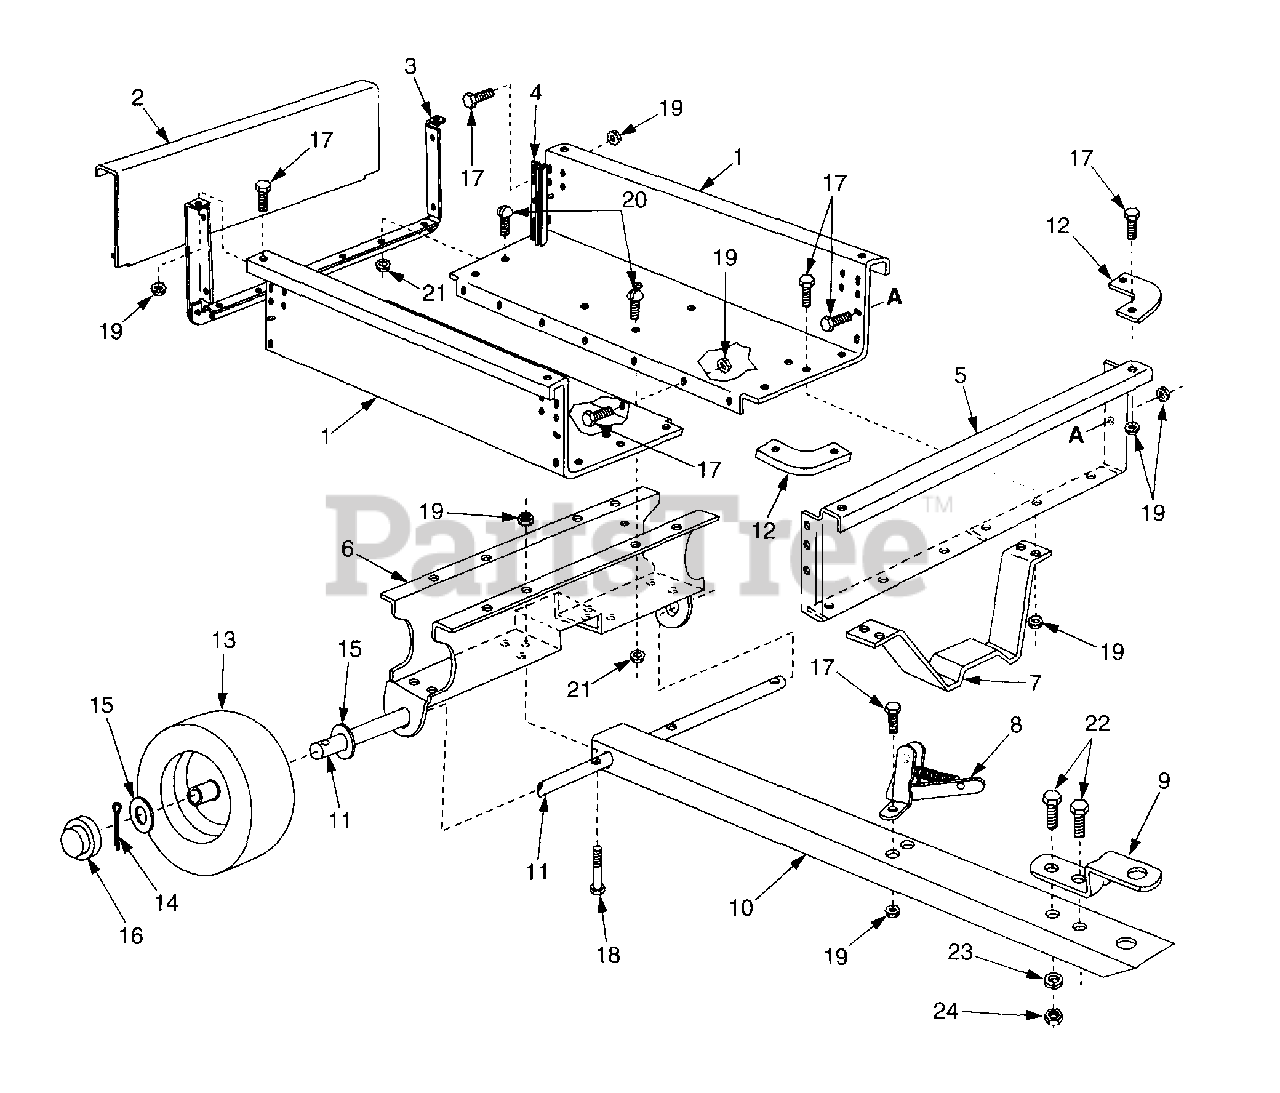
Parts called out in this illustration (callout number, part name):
15	Washer, Flat 3/4"
16	Hub Cap
17	Hex Bolt, 1/4-20 x 1/2"
18	Hex Bolt, 1/4-20 x 1-1/2"
19	Hex Nut, 1/4-20 Thread (Sems)
20	Slt. Truss Hd. Bolt 5/16-18 x 3/4" Lg.
21	Hex Nut, 5/16-18 Thread (Sems)
22	Hex Bolt, 3/8-16 x 1" Lg.
23	Lock Washer, 3/8"
24	Hex nut, 3/8-16 Thread
